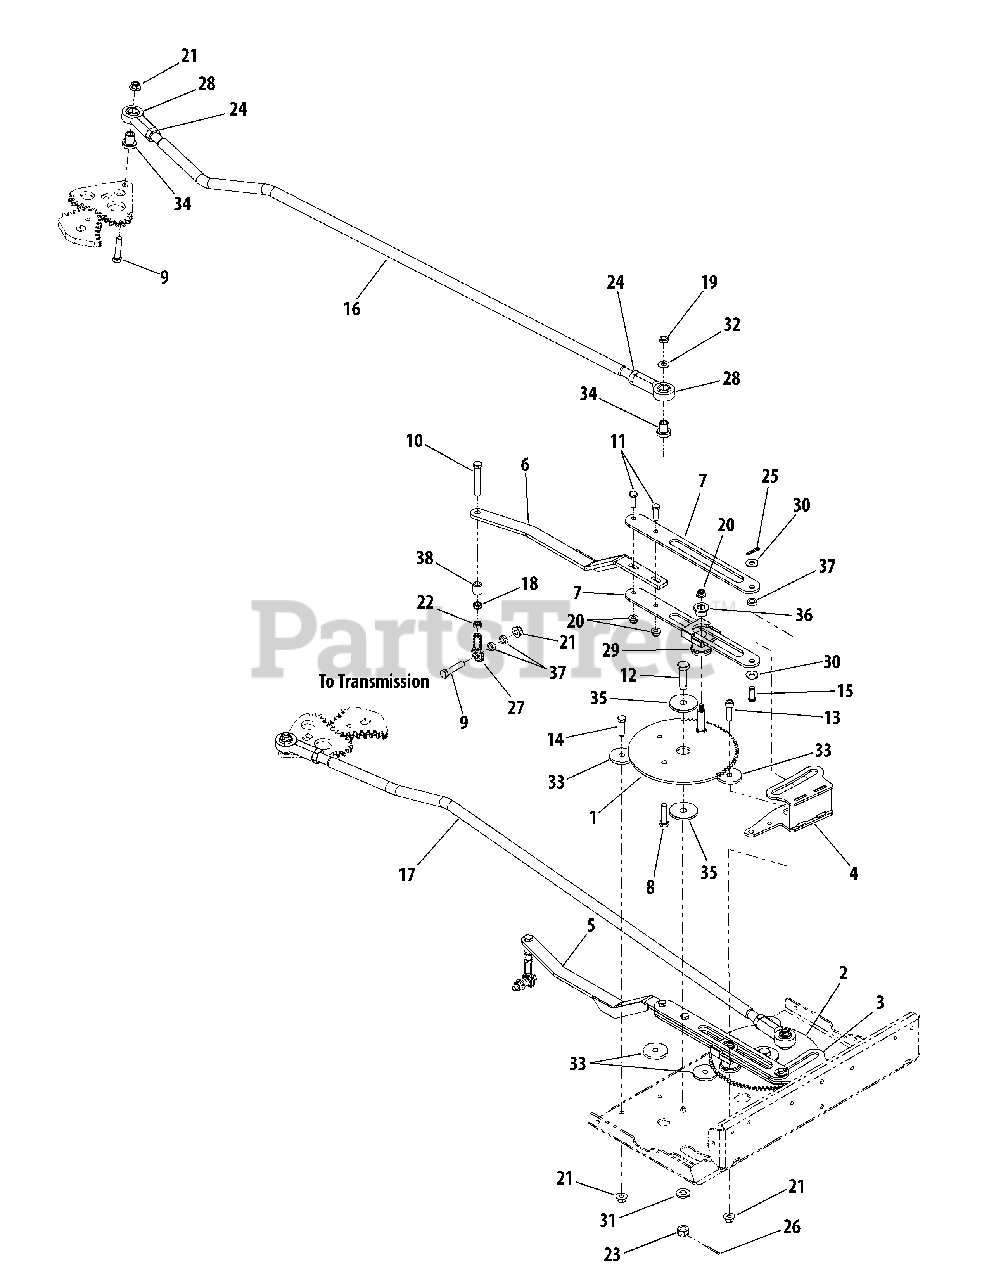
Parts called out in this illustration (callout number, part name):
1	Gear Assembly, Steering RH
2	Gear Assembly, Steering LH
8	Screw, Hex Cap, 3/8-16 x 1.5 Gr5
9	Screw, Hex Cap, 3/8-16 x 1.75 Gr5
10	Screw, Hex Cap, 3/8-24 x 2.5 Gr5
11	Screw, Hex Cap, 5/16-18 x 1.0 Gr5
11	Bolt, Carriage, 5/16-18 x 1.0
12	Screw, Hex Cap, 1/2-20 x 1.75 Gr5
13	Screw, Socket Hd., 3/8-16 x 1.25
14	Screw, Hex Cap, 3/8-16 x 1.25 Gr5
15	Pin, Clevis, .375 x .969
16	Link, Drag, RH
17	Link, Drag, LH
18	Nut, Hex Insert Jam Lock, 3/8-24 Gr5
19	Nut, Hex Jam Lock, 3/8-16 Gr5
20	Nut, Hex Insert Flange Lock, 5/16-18 GrF
21	Nut, Hex Insert Flange Lock, 3/16-16 GrF
22	Nut, Hex Jam, 3/8-24, Gr5
23	Nut, Hex Slotted, 1/2-20 Gr5
24	Nut, Hex Jam, 5/8-18, Gr5
25	Pin, Internal Cotter
26	Pin, Cotter, 3/32 x 1.0
27	End, Ball Joint Rod
28	Ball Joint, .625 ID x 5/8-18
29	Box, Steering Guide
30	Washer, Flat, .385 x .87 x .092
31	Washer, Flat, .51 x 1.0 x .125
32	Washer, Thrust, .375 x .812 x .06
33	Spacer, Shoulder, .884 x .19
34	Spacer, Shoulder, .3825 x .6175
35	Spacer, Shoulder, .979 x .2025
36	Bearing, Flange, .51 x .757
37	Spacer, .38 x .625 x .21
38	Spacer, .385 x .625 x .70
